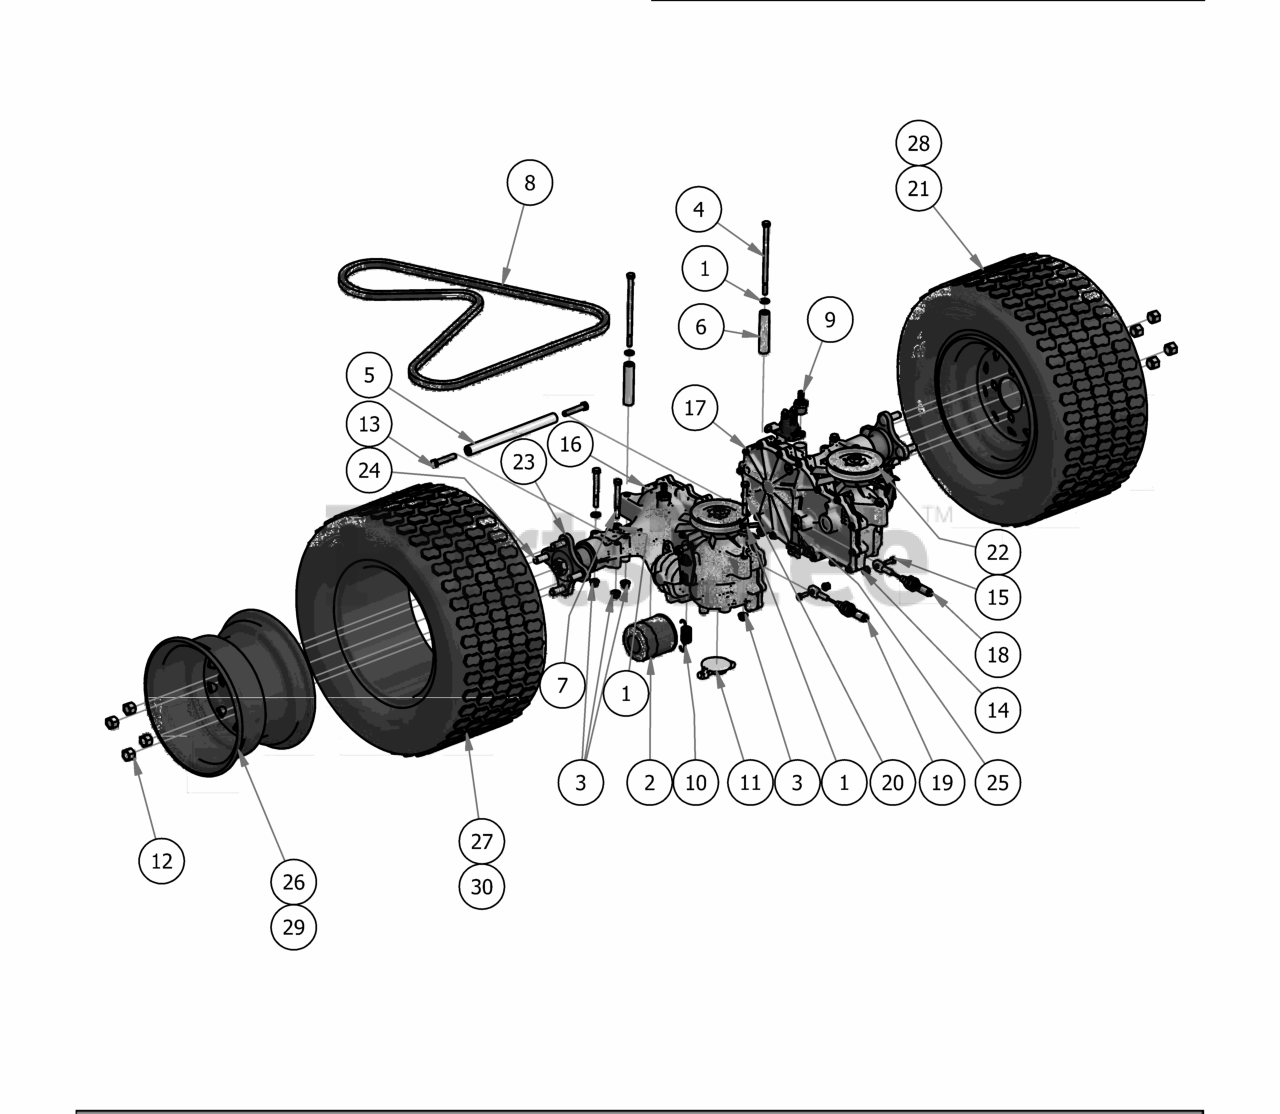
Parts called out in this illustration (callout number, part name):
1	5/16" Flat Washer
3	5/16-18 Nylon Flange Nut
4	5/16" x 6" Bolt
5	2017 Transaxle Spacer-ZT
6	2017 Transaxle Spacer
7	5/16" x 3" Hex Bolt
9	45 degree fitting
10	Transaxle Spring
11	ZT Transaxle Charge Plate/With O'Ring
12	Acorn Lug Nut
13	3/8'' x2'' Hex Bolt
14	1/4-20 Nylon Insert flange Nut
15	1/4" x 3/4" Hex Bolt
16	Right ZT Transaxle
17	Left ZT Transaxle
18	Brake Cable
19	Brake Cable
20	5/16" x 2 1/2" Bolt
21	ZT Tire and Rim Assembly 22 x 11 - 10
22	Fan/Pulley Kit for ZT
23	Transaxle Hub
24	Transaxle Wheel Studs
25	Transaxle Brake Lever
26	ZT Black Wheel Only
27	ZT Tire Only 22x-11-10
28	48" ZT Only Tire 22x10-10 Tire and Wheel
29	48" ZT Only 10" Black Wheel
30	48" ZT Only 22x10-10 Tire
